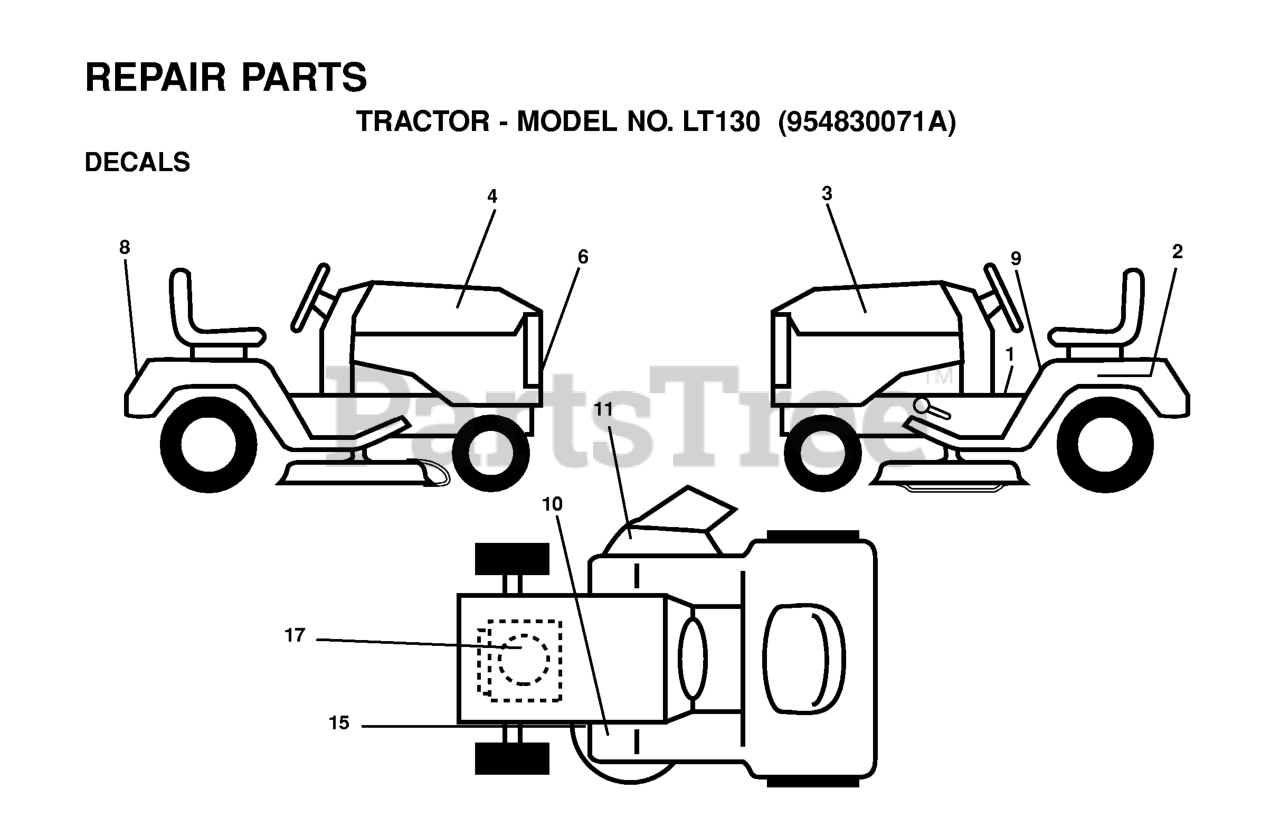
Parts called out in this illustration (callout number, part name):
1	DECAL DASH
2	DECAL BTRY SYMBOLS
3	DECAL HOOD LH LT130
4	DECAL HOOD RH LT130
6	DECAL.GRILLE.HUSQ
8	DECAL FENDER HUSQ
9	DECAL CAUTION
11	DECAL WARNING (ENGLISH/FRENCH)
15	DECAL V-BELT SCHEMATIC
17	DECAL HP ENGINE
